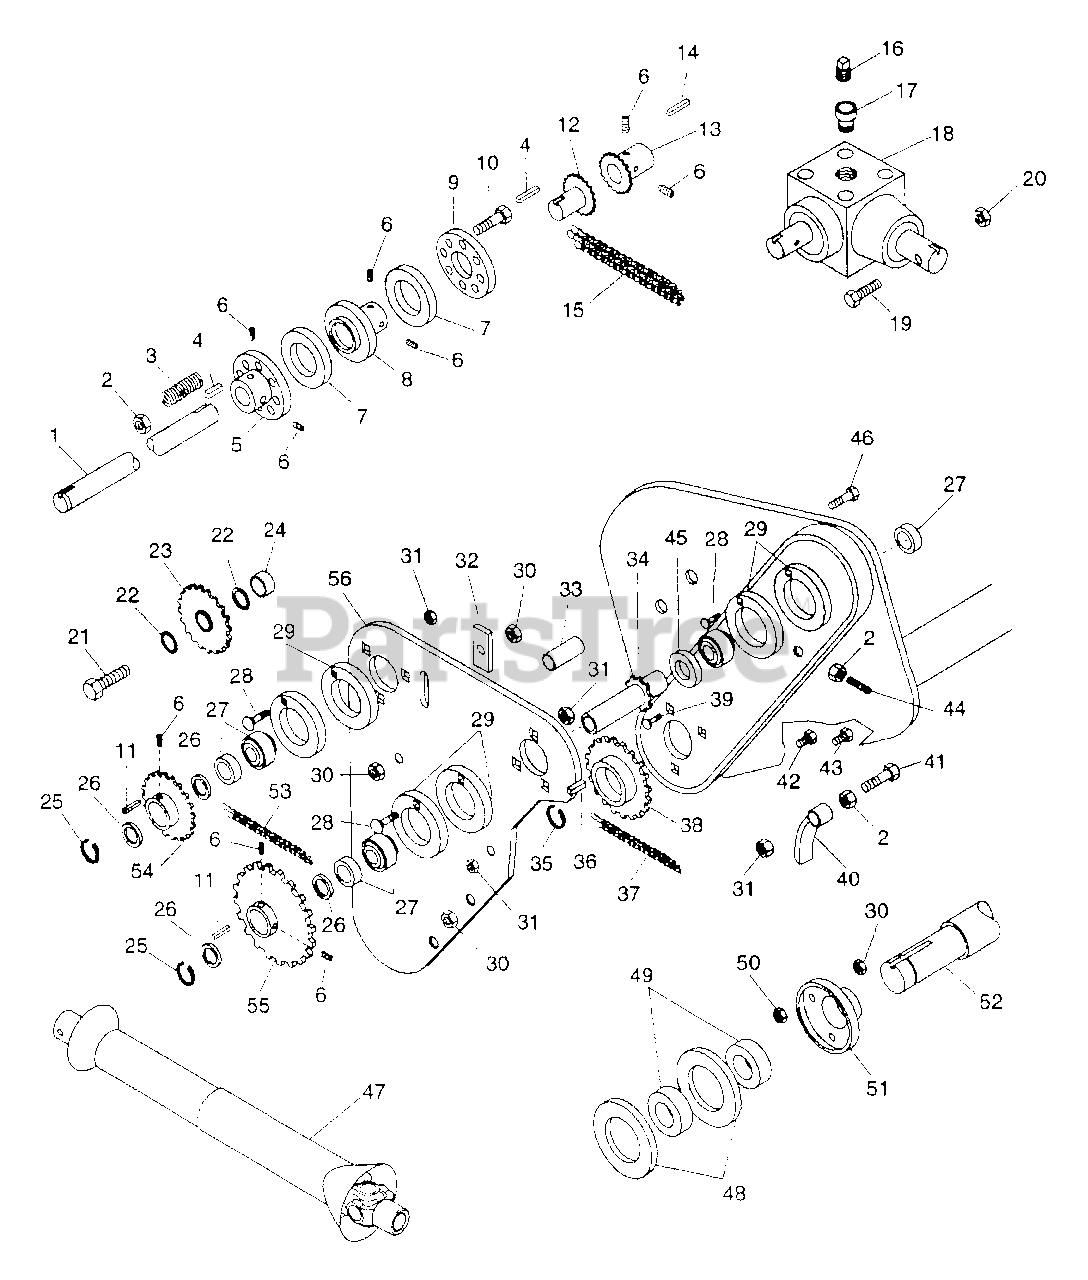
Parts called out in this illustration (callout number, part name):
1	DRIVE SHAFT
2	NUT-HEX .312-18
3	SG-COMP .135X.66X.75 WLD210
4	KEY-SQ .25 X 1.25 X .25 SAE
5	HUB-END PLATE
6	SCR-SET .32-18X.50 SKH
7	CLUTCH DISC
8	HUB-CENTER
9	PRESSURE PLATE
10	BLT-HEX .31-18X2.75 GR5
11	KEY-SQ .25X1.0X.25 SAE 8630
12	COUPLER-MALE HALF
13	COUPLER-FEMALE HALF
14	KEY-SQ .25 X 1.50 X .25 SAE
15	CHAIN-COUPLER
16	VENT PLUG
17	COUPLING
18	GEAR BOX ASSEMBLY
19	BLT-HEX .38-16X2.50 PL GR5
20	NUT-LK TOP .375-16 GR C YWZC
21	BLT-HEX .50-13X2.75 PL GR5
22	WSHR-FL-STL .505X1.000X.062
23	IDLER SPROCKET
24	SPACER-IDLER
25	RG-RTNG-EXT 1.00X.042
26	WSHR-FL-STL 1.015X1.500X.134
27	BRG-BALL 1.0X2.047X.59
28	BLT-RDHDSQNK.31-18X.75GR5SHTPL
29	FLANGETTE
30	NUT-LK-CROWN .50-13 GR C PL
31	NUT-LK-TOP .312-18 GR C PL
33	TUBE .512 X .747 X 2.00
34	SPROCKET SHAFT
35	RG-RTNG-EXT 1.500X.050
36	KEY-SQ .38X1.00X.375 SAE 1035
37	DRIVE CHAIN
38	DRIVEN SPROCKET
39	BLT-RDHDSQNK .50-13X1.50 PL
40	CHAIN TIGHTNER
41	BLT-HEX .31-18X2.75 GR2
42	CARRIAGE BOLT-SPECIAL
43	BLT-RDHDSQNK .38-16X2.25 SHTPL
44	SCR-SET .32-18X2.00 SKHCUP
45	SPACER 1.050X1.312X.410
46	BLT-HEX .50-13X3.00 PL GR2
47	UNIVERSAL DRIVE SHAFT
48	FLANGETTE-4 HOLE
49	BRG-BALL 1.50X80MMX1.7
50	NUT .50-13 PL
51	CAP-BEARING GUARD
52	TINE SHAFT
53	ROLLER CHAIN
54	SPROCKET 11T
55	SPROCKET 40 T
56	INNER COVER
